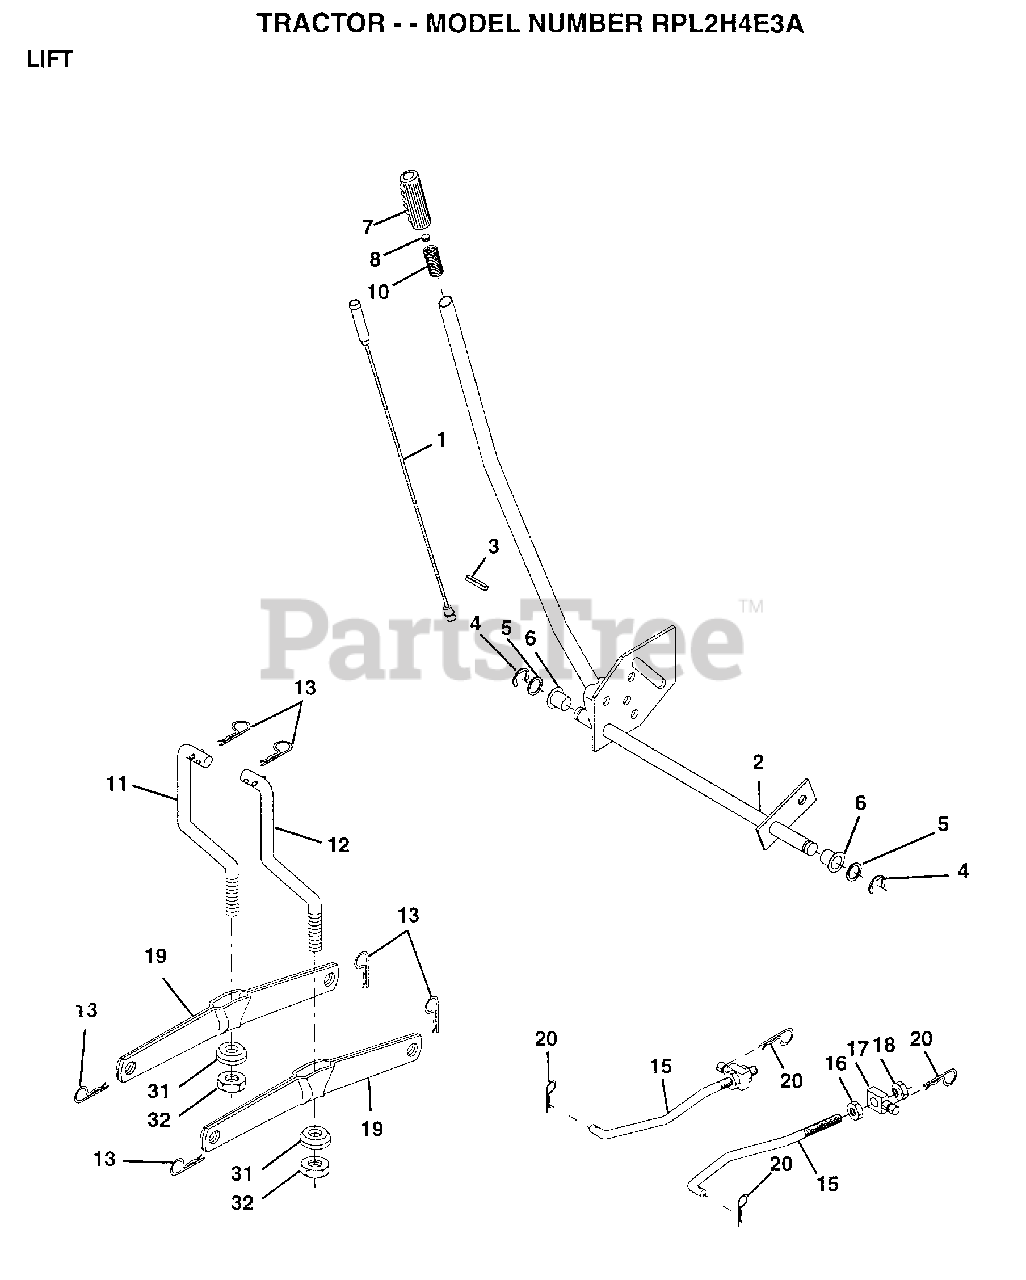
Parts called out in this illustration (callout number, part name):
1	WIRE ASM
2	HANDLE.LIFT.LH.
3	PIN GROOVE
5	WASHER
6	NYLON BEARING
7	GRIP
15	LINK.FRONT
16	NUT
17	TRUNION
18	NUT.LK.W/WSH.1/2.
19	ARM SUSP REAR
20	RETAINER.SPRING
31	BEARING PVT LH
32	NUT.CROWNLOCK.3/8
